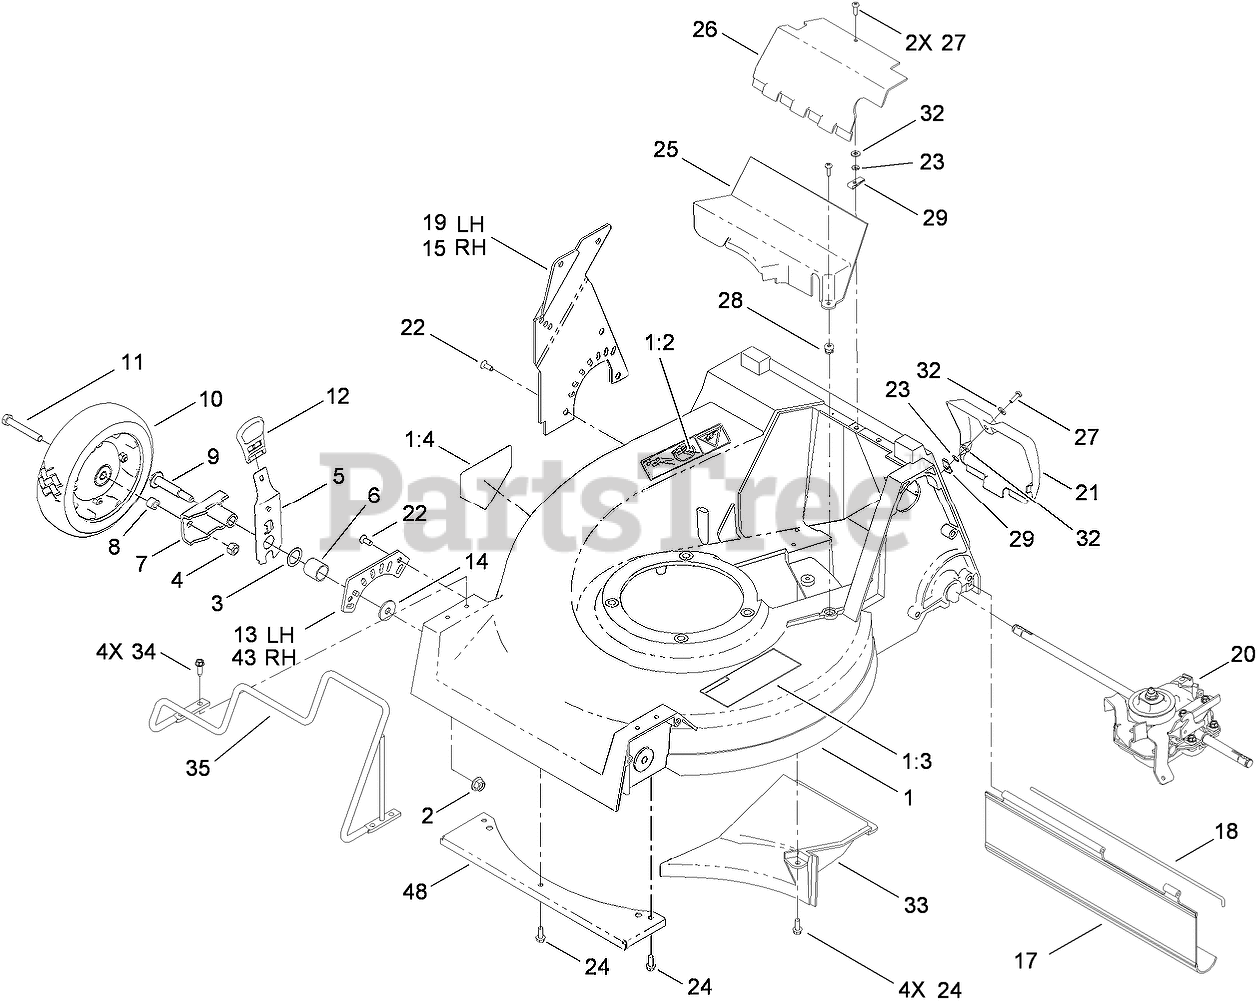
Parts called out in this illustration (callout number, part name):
1	DECK ASM
1:2	DECAL-DANGER
1:3	DECAL-DANGER
1:4	DECAL-DANGER
2	NUT-LOCK
3	WASHER
4	NUT-LOCK, CONE
5	FRONT SPRING ARM ASM
6	SPACER-BEARING
7	ARM-PIVOT, FRONT
8	SPACER-WHEEL
9	SCREW-SHOULDER
10	Wheel and Tire ASM
11	SCREW-HH
12	KNOB-HOC
13	PLATE-FRONT HOC, LH
14	WASHER
15	PLATE-REAR HOC, RH
17	SHEILD-TRAILING
18	ROD-SHIELD
19	PLATE-REAR HOC, LH
20	GEAR CASE ASM
21	DOOR-ACCESS, REAR
22	SCREW-HH
23	NUT-PUSH
24	SCREW-HWH
25	COVER-BELT, LOWER
26	COVER-BELT, UPPER
28	NUT-CLIP
29	NUT-TYPE J
32	WASHER-FLAT
33	BAFFLE-CHUTE, FLOOR
34	SCREW-HWHTF
35	ENGINE GUARD ASM
43	PLATE-FRONT HOC, RH
48	SHIELD-FRONT, HI-VAC
